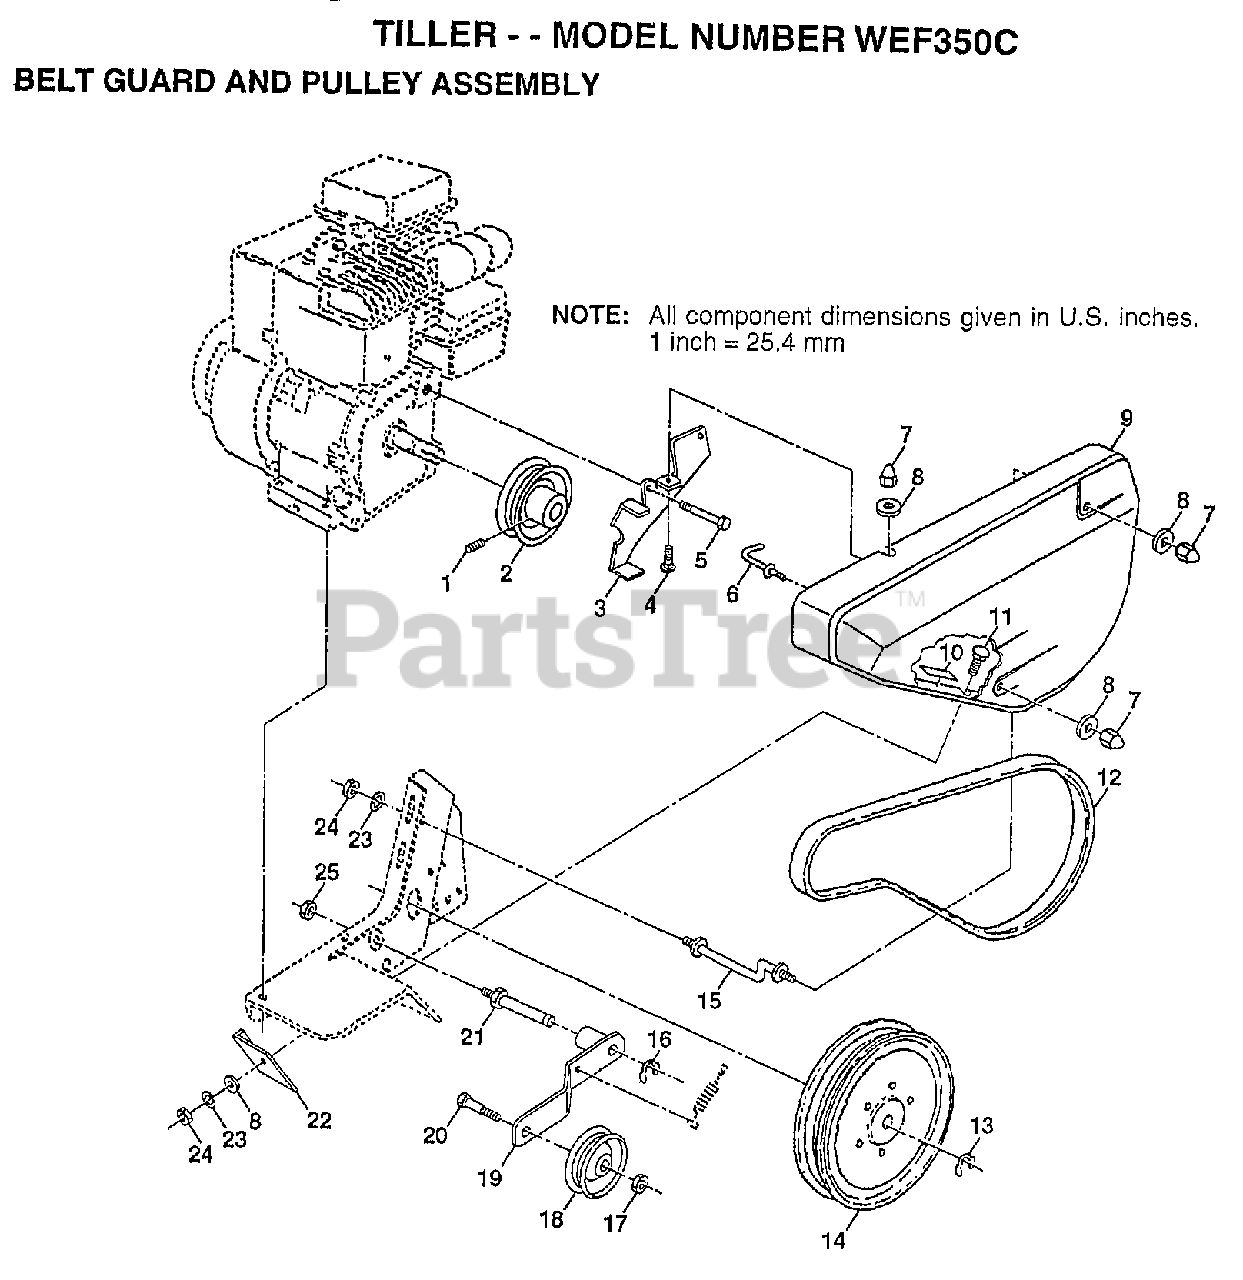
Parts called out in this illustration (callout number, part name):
1	SET SCREW
4	BOLT
7	NUT-CAP TI
8	WASHER
9	GUARD.BELT.TILLER
10	PAD IDLER TI
11	BOLT T
13	RING, RETAINER
14	PULLEY.TRANSMISSN
16	KLIP RING TI
17	NUT
19	IDLER ARM TI
21	SHAFT IDLER TI
22	SHIELD-DIRT TI
23	LOCKWASHER
25	JAM NUT TI
